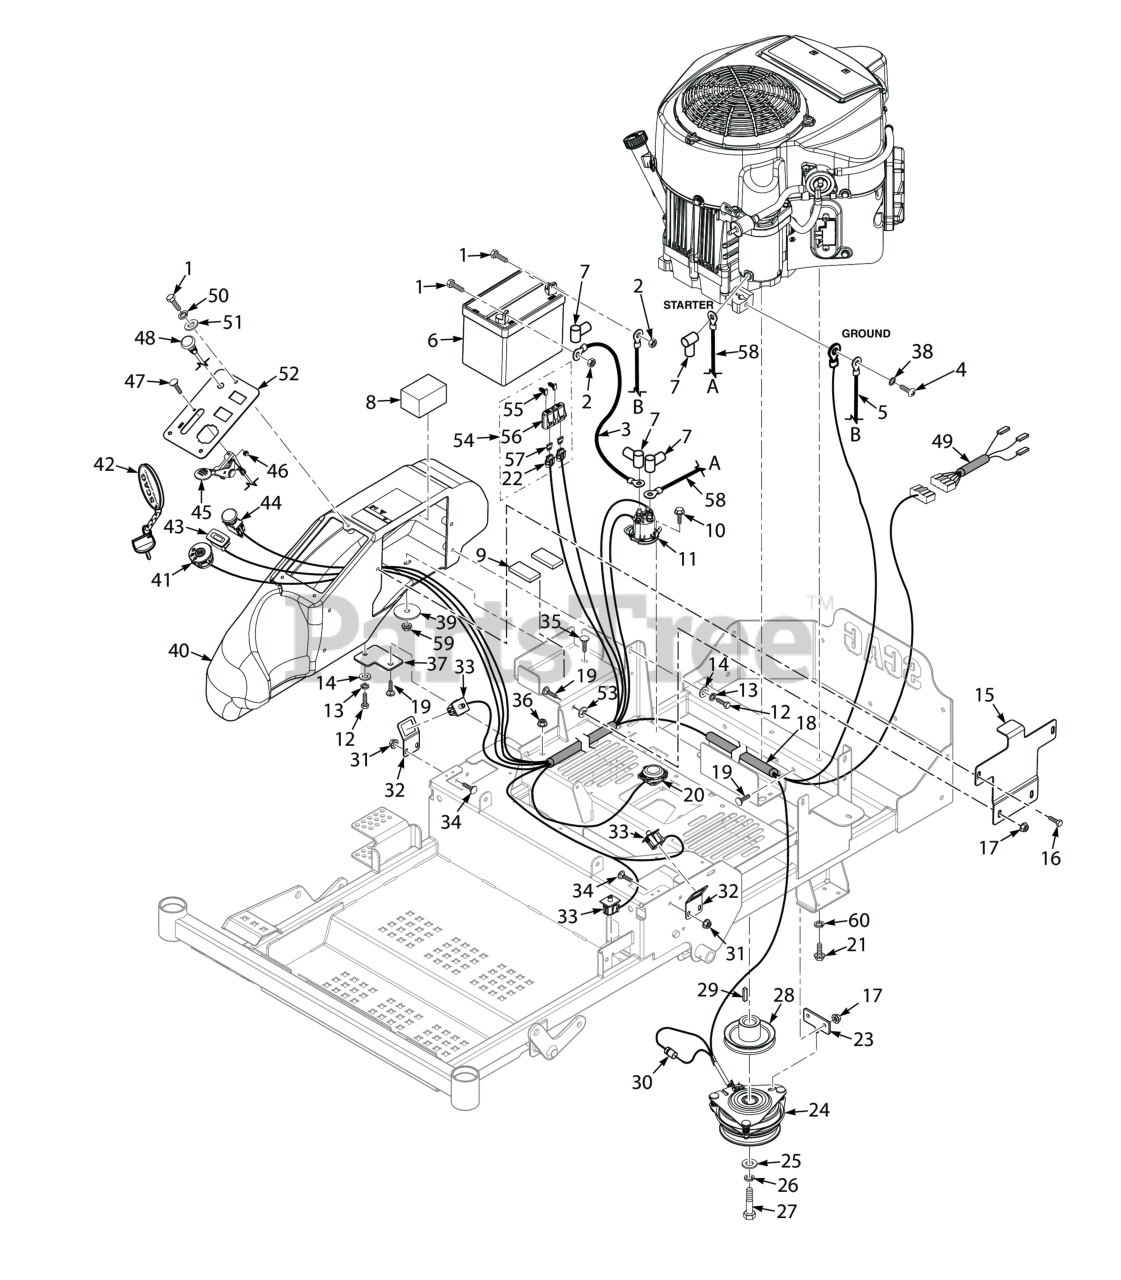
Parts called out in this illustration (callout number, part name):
1	Bolt, Hex Head 1/4-20 x .5" Battery, (Not Available Through Scag)
2	Nut, 1/4 - 20 Hex
3	Battery Cable, 18" Red w/Braid (25KA, 26DFI, 31DFI) - Kawasaki
4	Bolt, Hex Head M8 - 1.25 x 16 (48V / 52V)
5	Battery Cable, 31-1/2" Black (25KA, 26DFI, 31DFI) - Kawasaki
6	Battery, 12v - 230CCA
7	RUBBER BOOT
8	Pad, Battery - Rubber
9	Pad, Battery - Rubber
10	Screw, Self-Tapping 1/4-20 x 3/4
11	Solenoid, Sealed (Briggs & Stratton)
12	BOLT, SERRATED FLANGE HEX HEAD 5/16-18 X 3/4"
13	Lockwasher, 5/16 (.317 x .586 x .078) Helical Spring
14	Flatwasher, 5/16-.375 x .875 x .083 (35BV & 37BV-EFI)
15	Battery Hold Down
16	CAP SCREW, 5/16-18 X 1/2" SERRATED FLANGE HEX
17	Nut, Flange Head Elastic Stop 5/16-18
18	Wire Harness
19	Bolt, 5/16-18 x .75 RHSN Carriage
20	Switch, Double Pole - Twist
21	Bolt, Hex Head 3/8-16 x 1-1/4", Kawasaki FX / FT & FT-EFI
22	Fuse Holder Assembly
23	Plate, Anti-Rotation - Warner (SZL-48)
24	Clutch
25	Flatwasher, 7/16-.469 x 1.75 x .25 (48, 52)
26	Lockwasher, 7/16� Spring
27	Bolt, Hex Head 7/16-20 x 3¼" w/Patch
28	Pulley, 4-1/2" - 1" Bore
29	Key, 1/4 x 1/4 x 1.25" Pulley Mtg.
30	Diode, 600V 6 Amp
31	Nut, Flanged Elastic Stop 1/4-20
32	Bracket, Switch
33	Switch, Double Pole - Plunger
34	Serr. Fl. Hex Head CPSCR, 1/4-20 x 3/4"
35	Bolt, Carriage 5/16-18x1" (large frame units only)
36	Nut, Serrated Flange 5/16-18 (Right Front Engine Mounting, Briggs and Kohler Only)
37	Mounting Bracket, Fuel Tanks Front
38	Lockwasher, 5/16" Ext. Tooth (Kohler x1)
39	Flatwasher, 3/8-.406 x 2.25" x .1875
40	Console Tank, SZL
41	Ignition Switch
42	Key, Assembly w/Fob
43	Hour Meter, Inductive
44	Switch, PTO - 10 Amp
45	Throttle Cable, Briggs & Stratton
46	Nut, Elastic Stop #10-24
47	Bolt, Carriage #10-24 x 1/2"
48	Choke Cable, Briggs & Stratton
50	Lockwasher, 1/4� Spring
51	Flatwasher, 1/4" (.312 x .750 x .065")
52	Instrument Panel w/Decal
53	Nut, Push-On 5/16-18
54	Double Fuse Assy.
55	Clip, Fuse Holder
56	Cover, Sealed Double
57	FUSE, 20 AMP BLADE TYPE AUTOMOTIVE
58	Battery Cable, 18" Red w/Braid (25KA, 26DFI, 31DFI) - Kawasaki
59	HEX NUT, ELASTIC STOP LOCK, 5/16-18
60	Lockwasher, 3/8" Spring, Kawasaki FX / FT & FT-EFI / B&S 32BV
